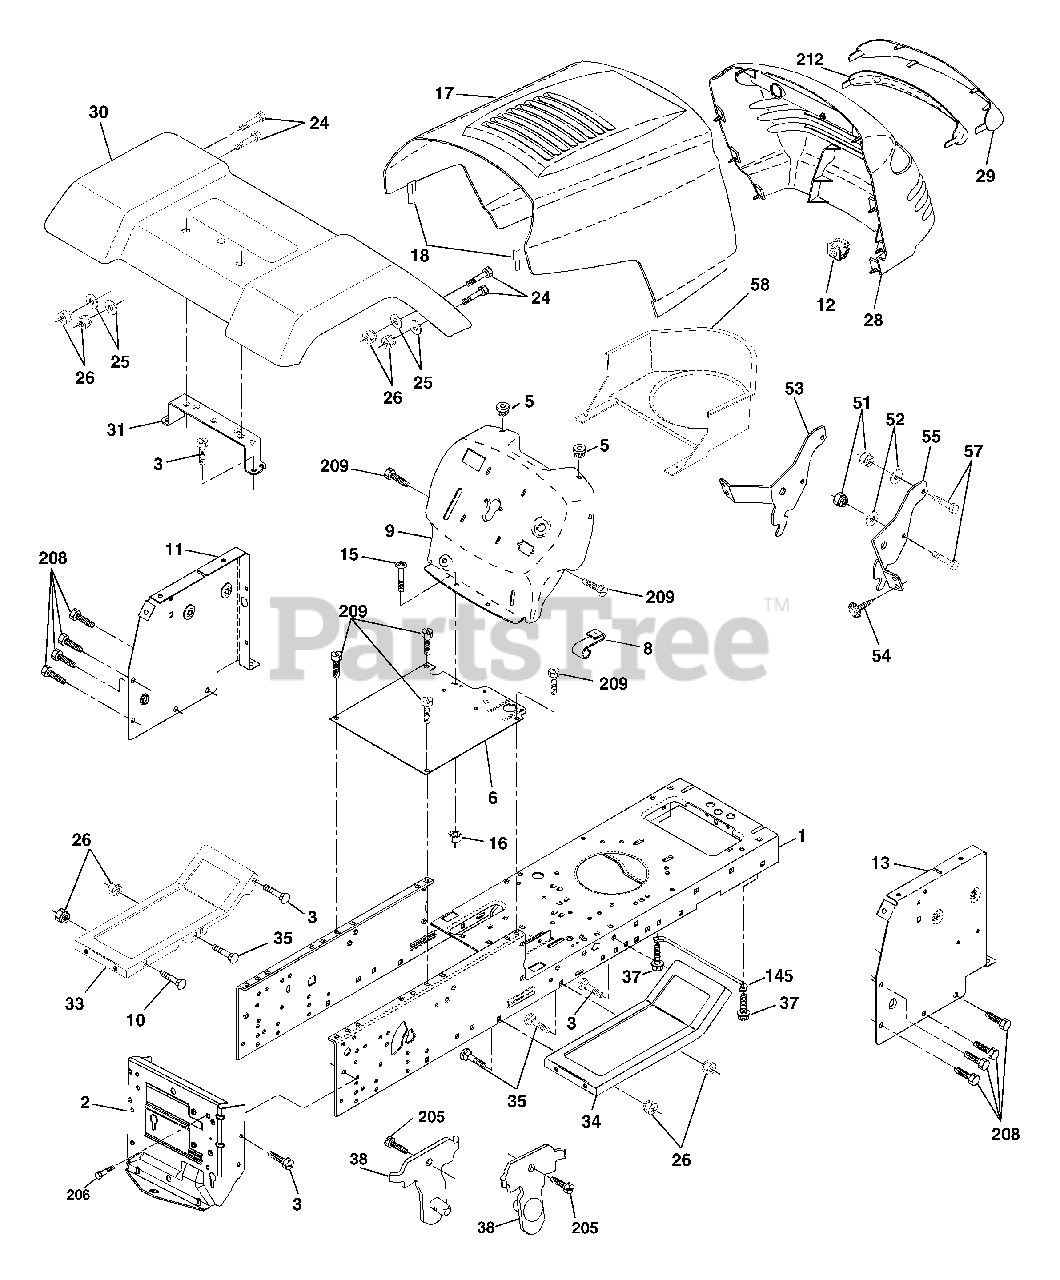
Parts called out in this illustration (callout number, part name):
1	Chassis
2	Drawbar
3	Screw 3/8-16 x 3/4
5	Bumper Hood/Dash
6	Saddle Slkscr Flat Lt 6 Sp
8	Clip Retainer Slide-On
9	Dash
10	Bolt Rd Hd Sqnk. 3/8-16 Unc x 1
11	Panel Asm. Dash Lh
12	Clip Tinnerman Grile P/L
13	Panel Dash Rh
15	Screw Mach Trhd 5/16-18 Unc x 3/4
16	Nut Keps 5/16-18 Unc
17	Hood
18	Bumper Hood
24	Bolt Fin Hex 3/8-16 Unc x 1 Gr. 5
25	Washer 13/32 x 13/16 x 12 Ga.
26	Nut Lock Hex w/Insert 3/8-16 UNC
28	Grill/Lens Asm
29	Lens Grille Private label
30	Fender Asm
31	Bracket Fender
33	Footrest LH
34	Footrest RH
35	Bolt Rd Hd Sht. Sqnk. 3/8-16 x 3/4
37	Screw Thdrol 5/16-18 x 1/2 Tyt
38	Bracket Asm. Pivot Mower Rear
51	Nut Lock Hex W/Ins. 1/4-20
52	Washer 9/32 x 7/8 x 16 Ga.
53	Bracket Grille LH
54	Screw Hex Wshd 8-18 x 7/8
55	Bracket, Grille RH
57	Bolt Fin Hex 1/4-20 x .75
58	Air Duct Private Label
145	Rod Pivot Chassis/Hood
205	Screw Thdrol 3/8-16 x 1/2
206	Bolt shoulder 5/16-18
208	Screw Thdrol 3/8-16 x 1/2
209	Screw Hex Wsh Thdrol 3/8-16
212	Insert Lens Reflector
212	Plug Btn Blk
